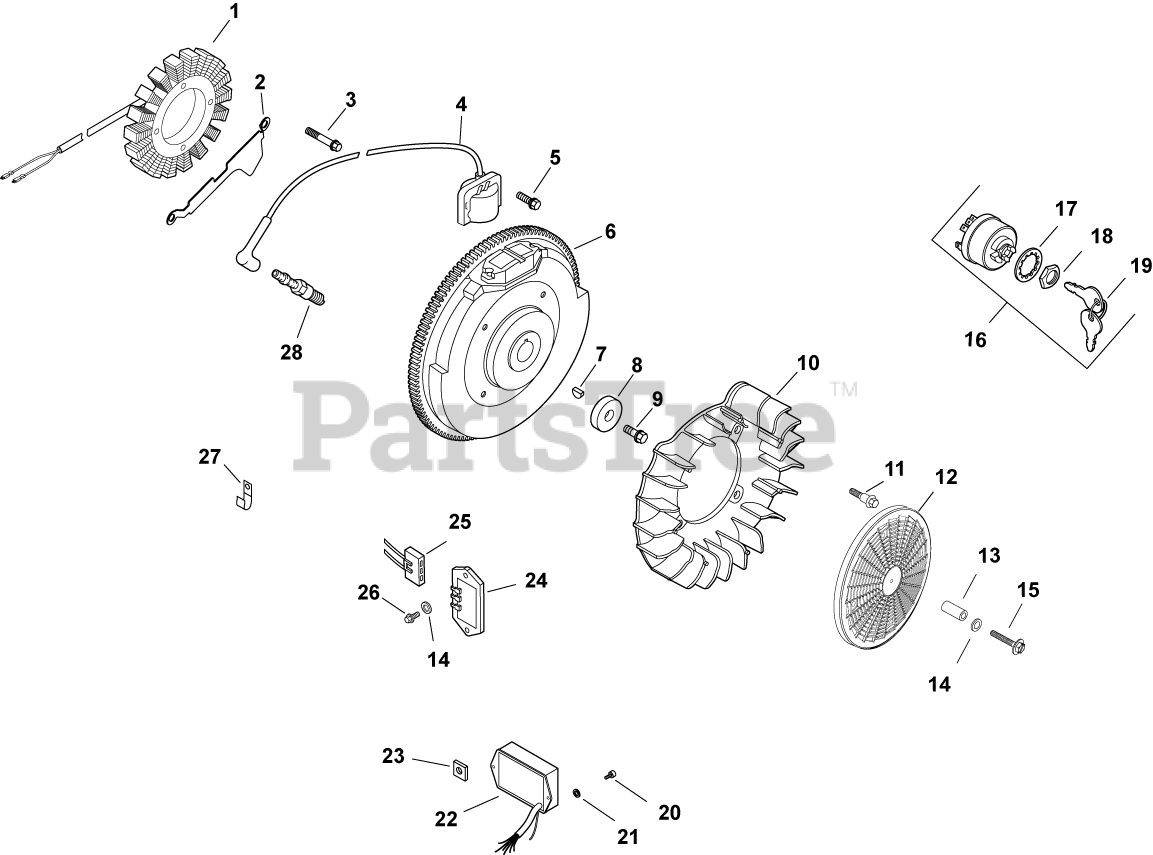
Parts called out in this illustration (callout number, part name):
1	KIT, 15 / 20 AMP STATOR
2	BRACKET, STATOR WIRE
3	SCREW, M5X0.8X25 - (#25086402S)
4	MODULE, IGNITION
5	SCREW, SKT THD FRM M5X0.8X25
6	FLYWHEEL, PAINTED-USE 24 025 57-S
7	KEY, 3/16" X 5/8"
8	WASHER, FLAT 13/32"
9	SCREW, FLG M10X1.5X45 - (#25086361S)
10	FAN USE 24 157 11-S
11	BOLT, SHOULDER
12	SCREEN, GRASS-USE 24 162 45-S
13	SPACER - DISCONTINUED
14	WASHER, FLAT 3/16"
15	SCREW, SLT HD CAP M4X0.7X25
16	SWITCH ASSY, KEY (KM)-USE 25 099 32-S
17	WASHER, INTERNAL TOOTH
18	NUT, KEY SWITCH
19	KEY, SET -USE 48 340 01-S
20	SCREW, PHL HD #11-16X1/2"
21	WASHER, FLAT 1/4" (O.D. 1/2")
22	MODULE, SPEED ADVANCE-DISCONTINUED SEE PB265
23	NUT, PLASTIC
24	REG/RECTIFIER (20/25 AMP)-USE 25 403 20-
25	CONNECTOR, BODY (KM)-USE 25 155 41-S
26	SCREW, PHL HD #11-16X7/8"
27	CLIP, CABLE
28	PLUG, SPARK (PRO SERIES)
